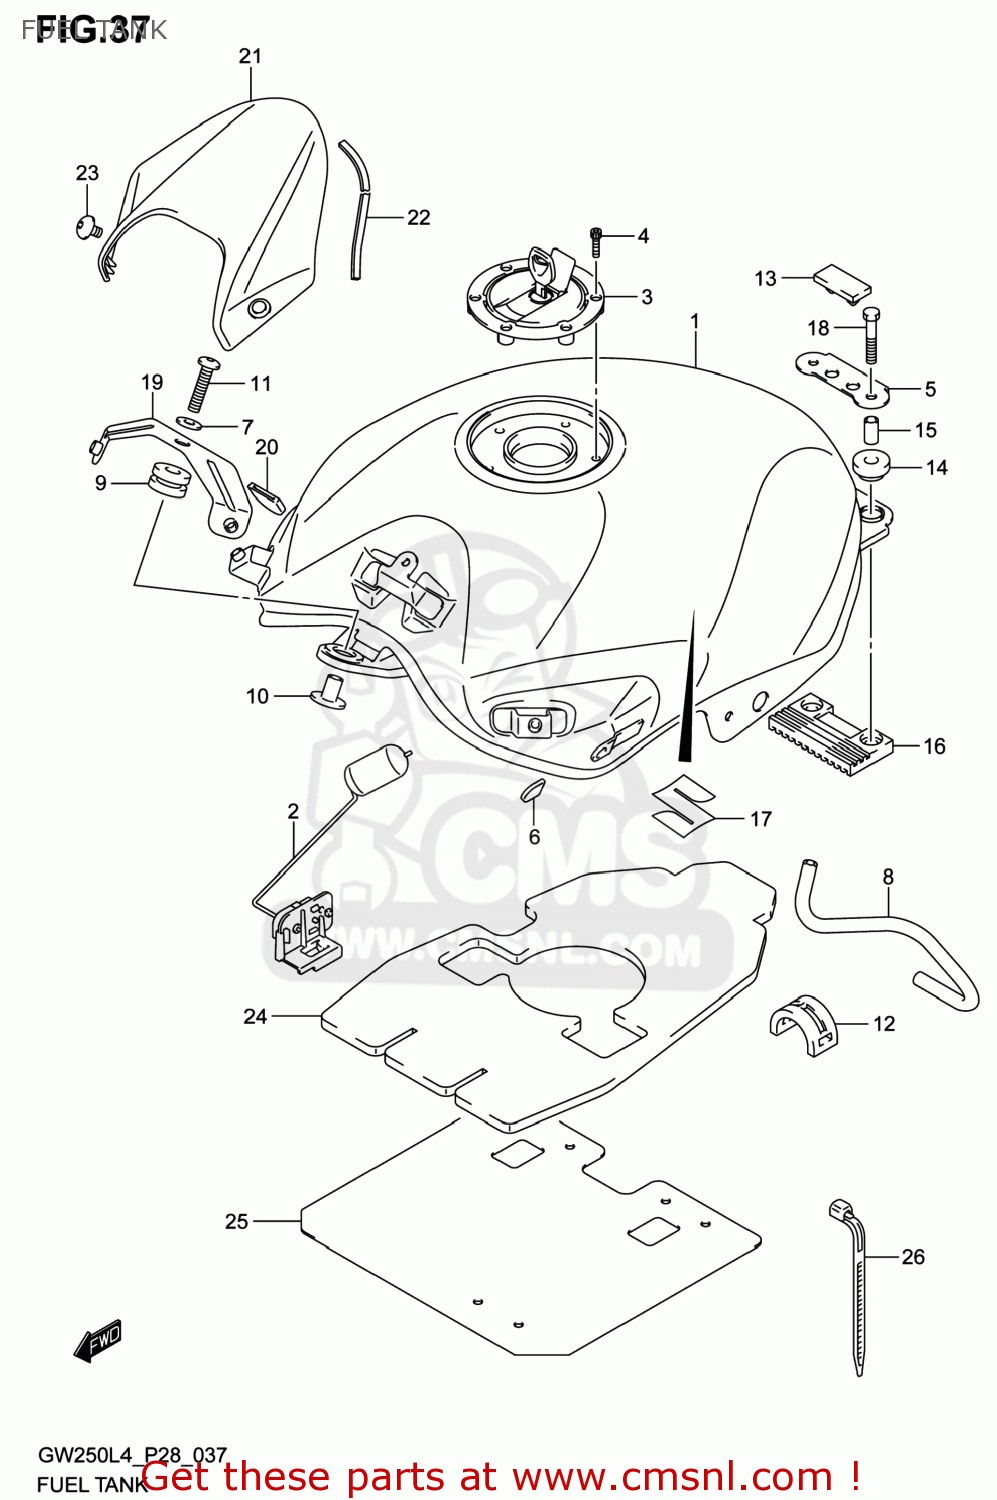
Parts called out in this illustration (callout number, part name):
1	TANK ASSY,FUEL(RED)
2	GAUGE ASSY,FUEL LEVEL SENDER
3	CAP SET,FUEL TANK
4	BOLT(5X20)
5	WASHER,FUEL TANK RR BRKT
6	CUSHION,FUEL TANK COVER
7	WASHER,FUEL TANK FR
8	HOSE,FUEL TANK WATER DRAIN
9	CUSHION,FUEL TANK FR
10	SPACER,FUEL TANK FR
11	SCREW,FUEL TANK FR
12	CUSHION,FUEL TANK SIDE
13	CUSHION,FUEL TANK RR BRKT
14	CUSHION,FUEL TANK RR UPR
15	SPACER,FUEL TANK RR
16	CUSHION,FUEL TANK RR LWR
17	EMBLEM,S
18	BOLT
19	BRACKET,FUEL TANK COVER
20	CUSHION,FUEL TANK COVER BRKT
21	COVER,FUEL TANK CTR
22	CUSHION,FUEL TANK COVER CTR
23	SCREW(6X10)
24	SHIELD,FUEL TANK HEAT
25	SHIELD,FUEL TANK HEAT NO.2
26	CLAMP,WIRING HARNESS
